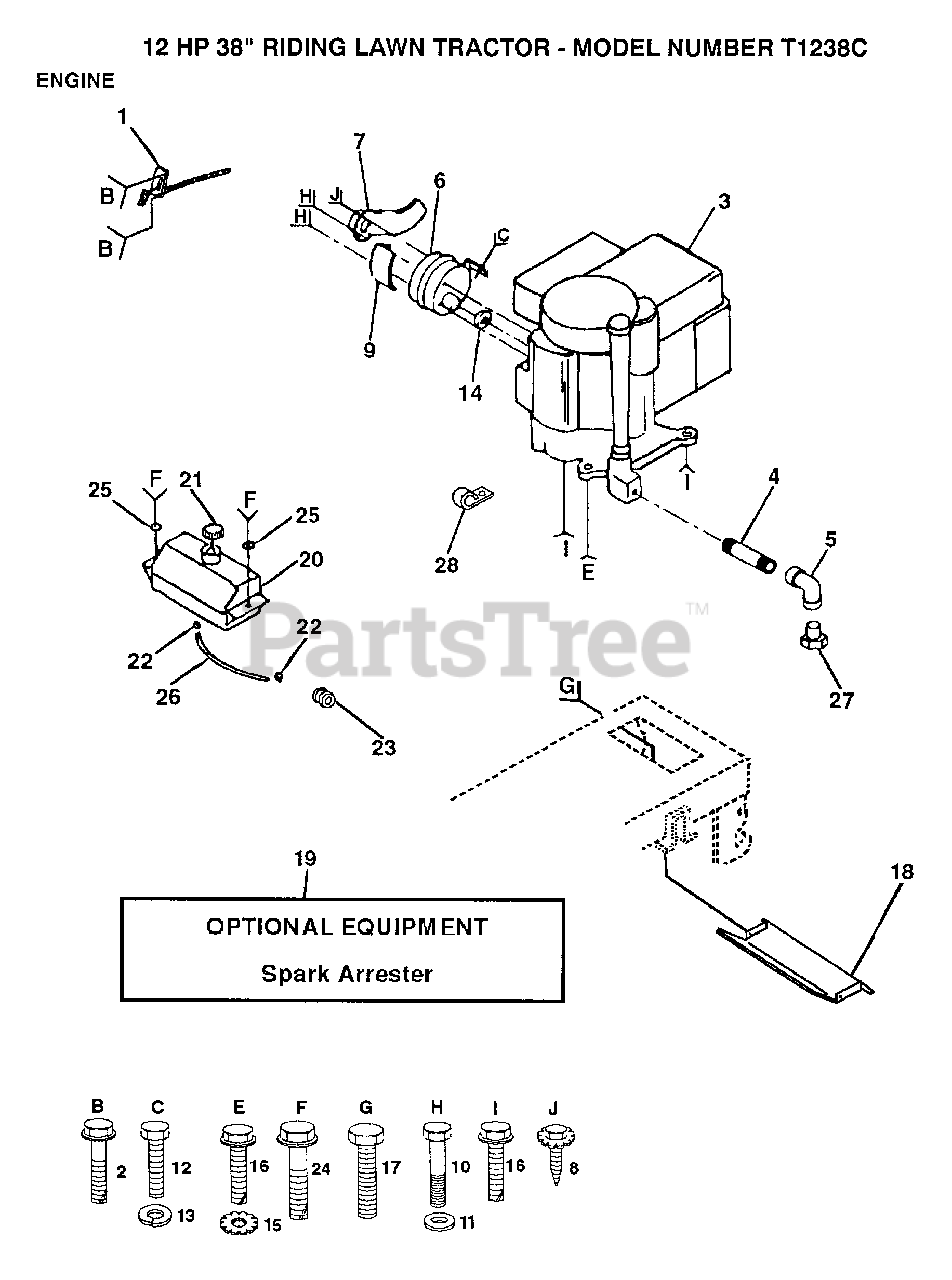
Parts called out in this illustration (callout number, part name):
2	SCREW LT
3	ENGINE BRIGGS AND STRATTON
4	PIPE NIPPLE
5	ELBOW
6	MUFFLER LTV
7	DEFLECTOR MUFFLER
9	SHIELD HEAT LTV
10	"BOLT,HEX"
11	WASHER T
12	BOLT
13	LOCKWASHER
15	LOCKWASHER
16	SCREW
17	SCREW
18	HEAT SHIELD
20	TANK.FUEL.LT.
22	HOSE CLAMP
24	SCREW
25	WASHER GT
26	FUEL LINE T
28	CLIP T
